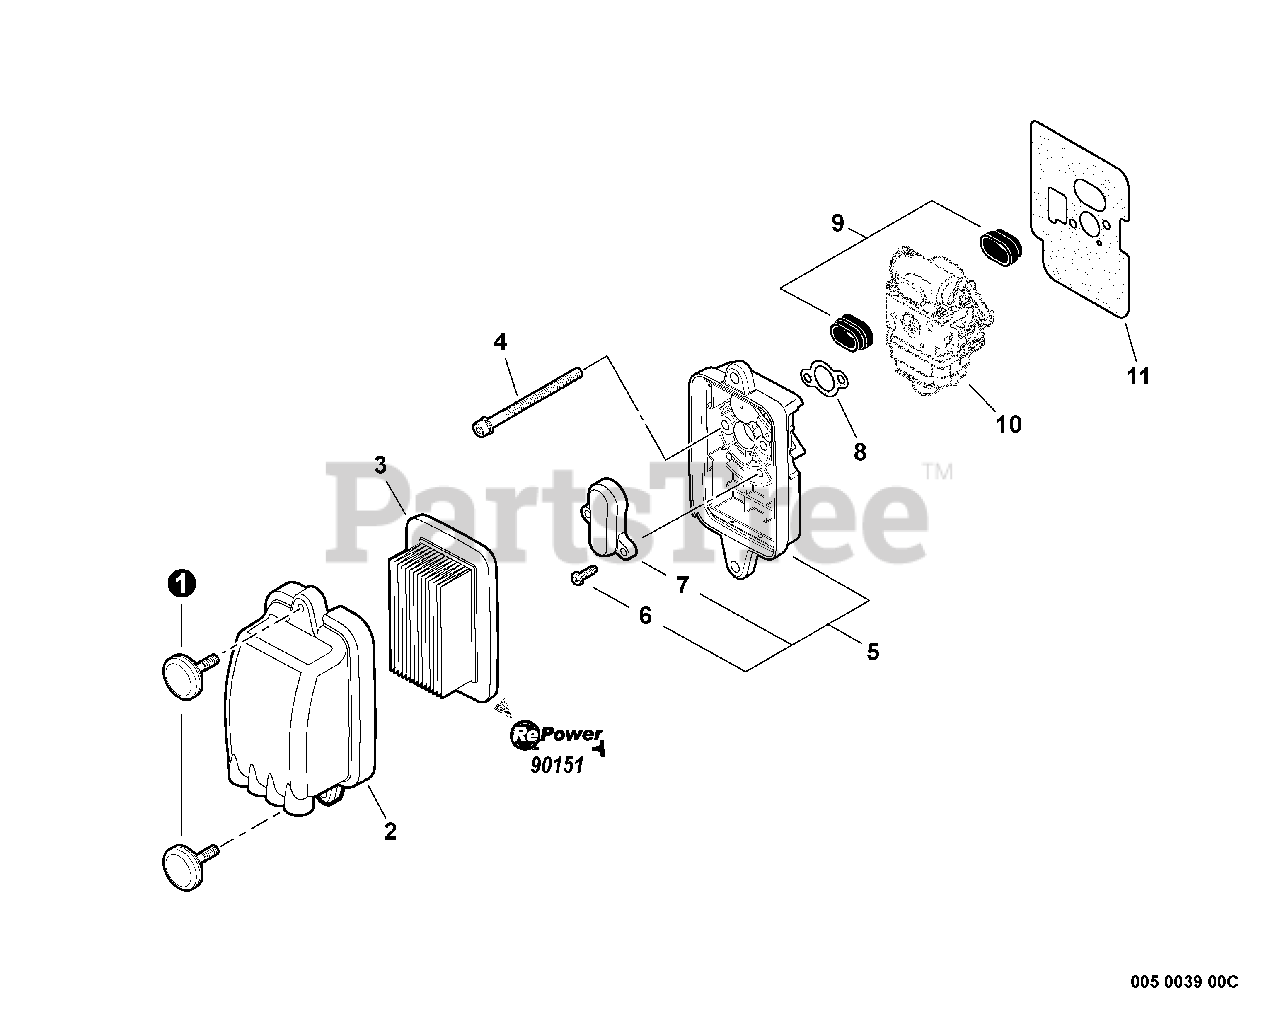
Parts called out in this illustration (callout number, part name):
1	THUMBSCREW
2	COVER, AIR FILTER
3	FILTER, AIR
4	SCREW 5×65
5	CASE ASSY, AIR FILTER
6	SCREW TAPPING 4×14
7	PLATE, PREVENT
8	GASKET, INTAKE
9	CONNECTOR
10	CARBURETOR
11	GASKET, INTAKE
12	TUNE-UP KIT - REPOWER
